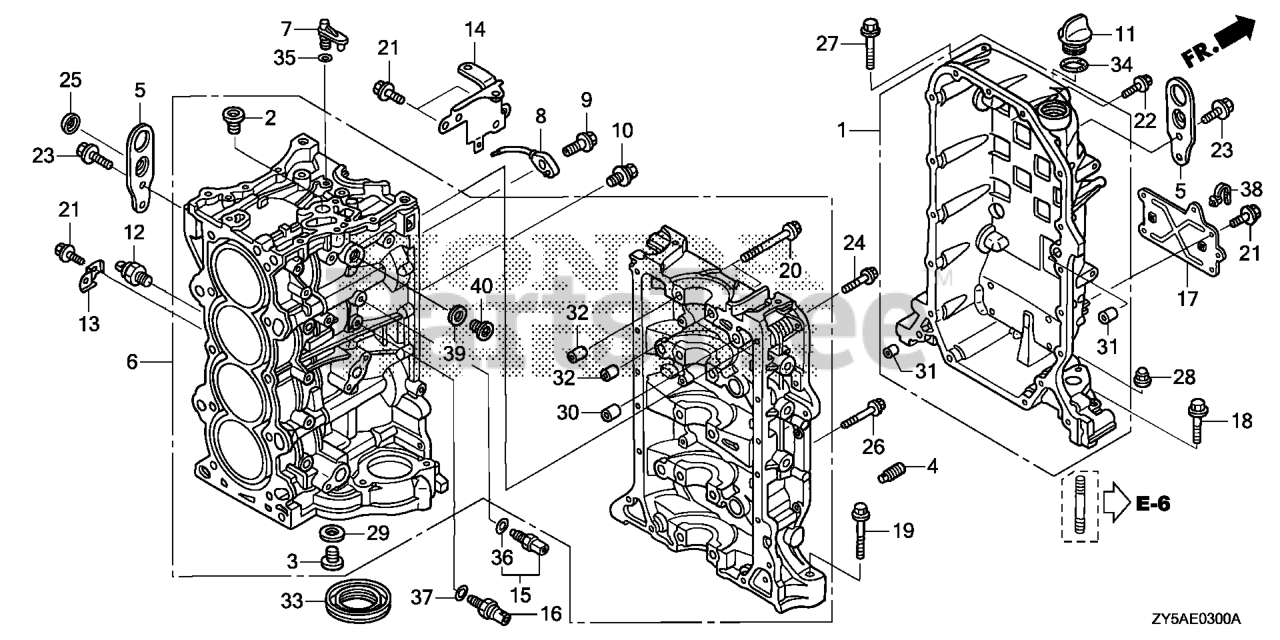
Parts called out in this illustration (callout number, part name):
1	CRANKCASE
2	BOLT, SEALING (20MM)
3	BOLT, SEALING (28MM)
4	ORIFICE, BLOCK (LOWER)
5	HANGER, ENGINE
6	BLOCK ASSY., CYLINDER *NH8* (DARK GRAY)
6	BLOCK ASSY. *NH8*
7	ORIFICE, OIL JET
8	BODY, OIL JET
9	BOLT, OIL JET
10	BOLT-WASHER (8X10)
11	CAP, OIL
12	SENSOR ASSY., KNOCK
13	BRACKET, CLIP B
14	BRACKET D, HARNESS CLIP
15	SENSOR ASSY., WATER TEMPERATURE
16	SENSOR, OIL PRESSURE
17	BRACKET, RELAY
18	BOLT, FLANGE (8X55)
19	BOLT, FLANGE (12X83)
20	BOLT-WASHER (11X95)
21	BOLT, FLANGE (6X14) (CT200)
22	BOLT, FLANGE (6X25)
23	BOLT, FLANGE (8X20)
24	BOLT, FLANGE (8X35)
25	CAP, BOLT (8MM)
26	BOLT, FLANGE (8X50)
27	BOLT, FLANGE (10X70)
28	NUT (10MM)
28	NUT, FLANGE CAP (10MM)
29	WASHER, SEALING (28MM)
30	PIN, DOWEL (18X22)
31	PIN, DOWEL (13X20)
32	PIN, DOWEL (13X14)
33	OIL SEAL (80X98X10) (ARAI)
34	O-RING (26X2.7)
35	O-RING (6.5X1.5)
36	O-RING (9.5X1.9)
37	O-RING (13X1.5) (ARAI)
38	CLIP, HARNESS BAND (145MM) (BLACK)
39	WASHER, SEALING (22MM)
40	BOLT, SEALING (22MM)
